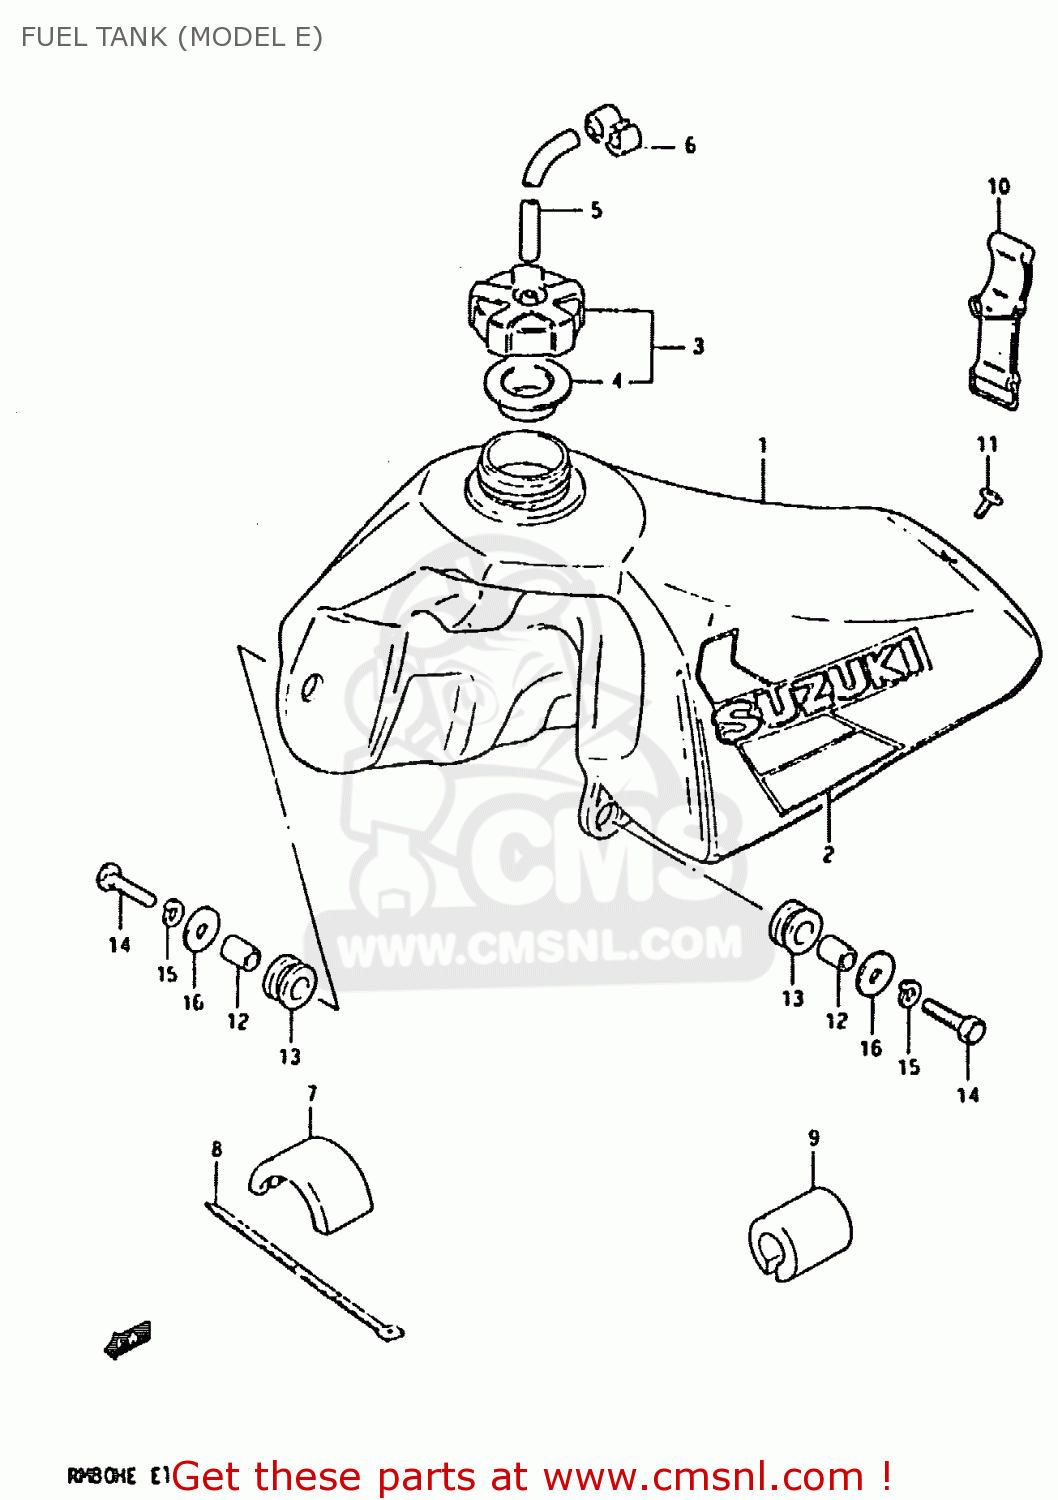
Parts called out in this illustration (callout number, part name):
1	TANK ASSEMBLY,FUEL
2	TAPE SET,FUEL TANK
3	CAP SET,FUEL TANK
4	GASKET,FUEL TANK CAP (NAS)
5	HOSE
6	CLAMP,BREATHER HOSE
7	CUSHION,FUEL TANK UPR FR
8	CLAMP
9	CUSHION, UPPER REAR
10	BAND
11	SCREW (6X15)
12	SPACER (6.8X10X11.5)
13	CUSHION
14	BOLT
15	LOCK WASHER
16	WASHER (6.5X24X1.6)
